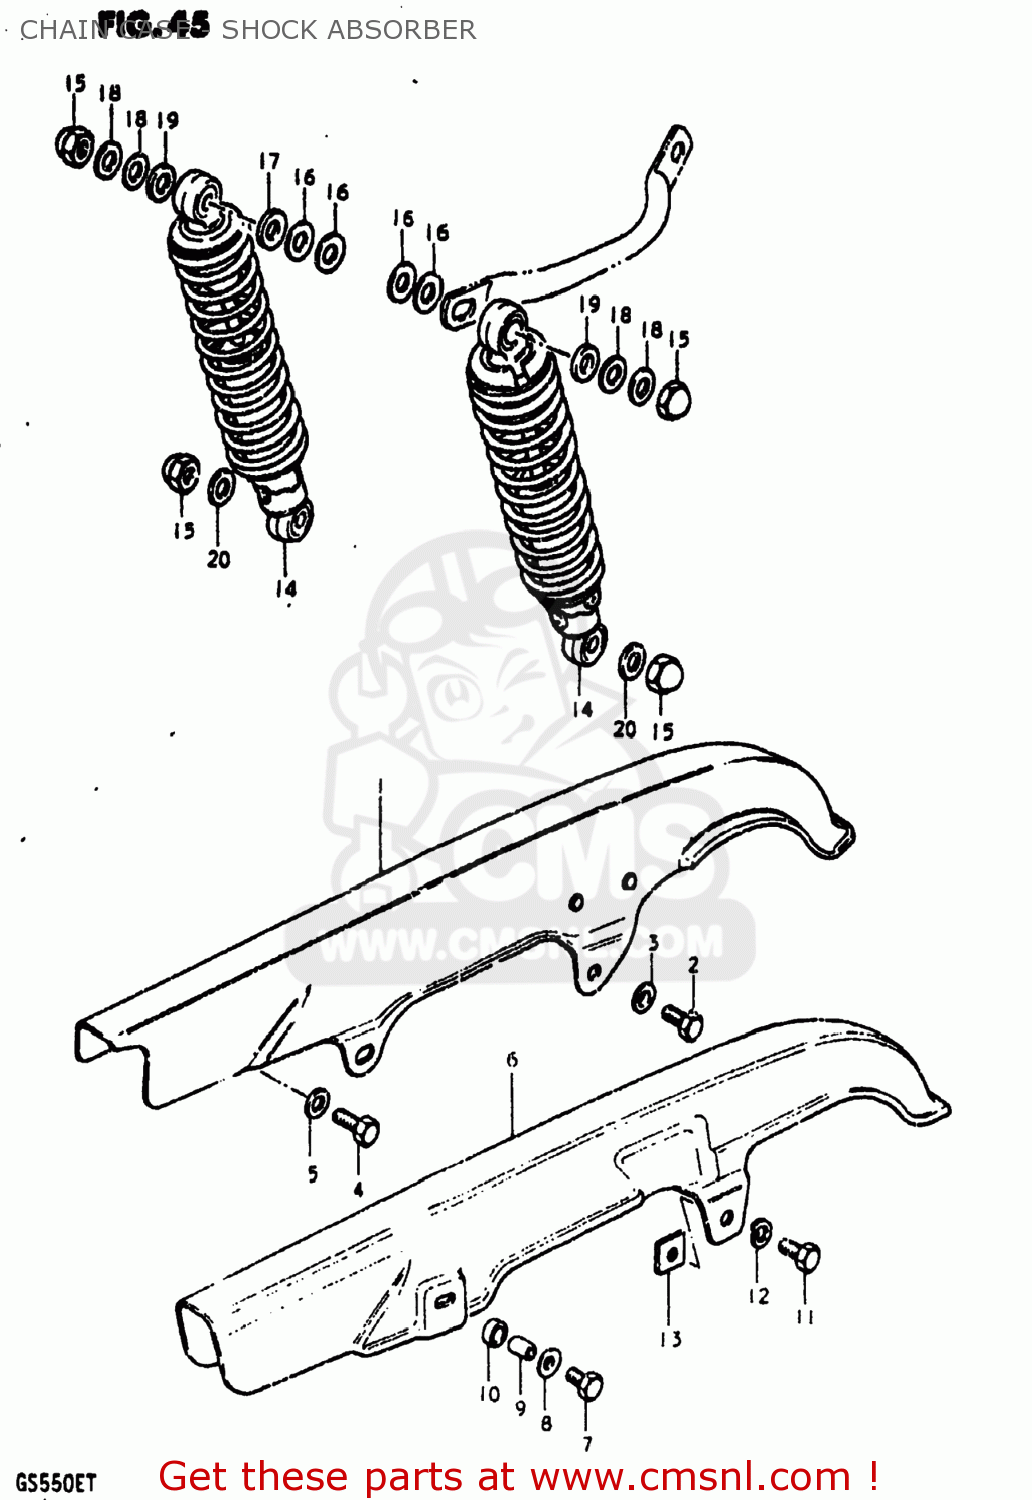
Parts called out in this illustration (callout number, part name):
1	CASE,CHAIN
2	BOLT(6X8)
3	WASHER
4	BOLT
5	WASHER(6.5X18X1)
6	CASE,CHAIN
7	BOLT
8	WASHER(6.5X18X1)
9	SPACER (6.1X8X5.2)
10	CUSHION
11	BOLT, UPPER
12	LOCK WASHER
13	NUT,CHAIN CASE RR
14	ABSORBER ASSEMBLY,REAR SHOCK
15	NUT, LOWER LH
16	WASHER
17	WASHER (12.5X24X3.2)
18	WASHER
19	WASHER(10.5X24X3.2)
20	WASHER
